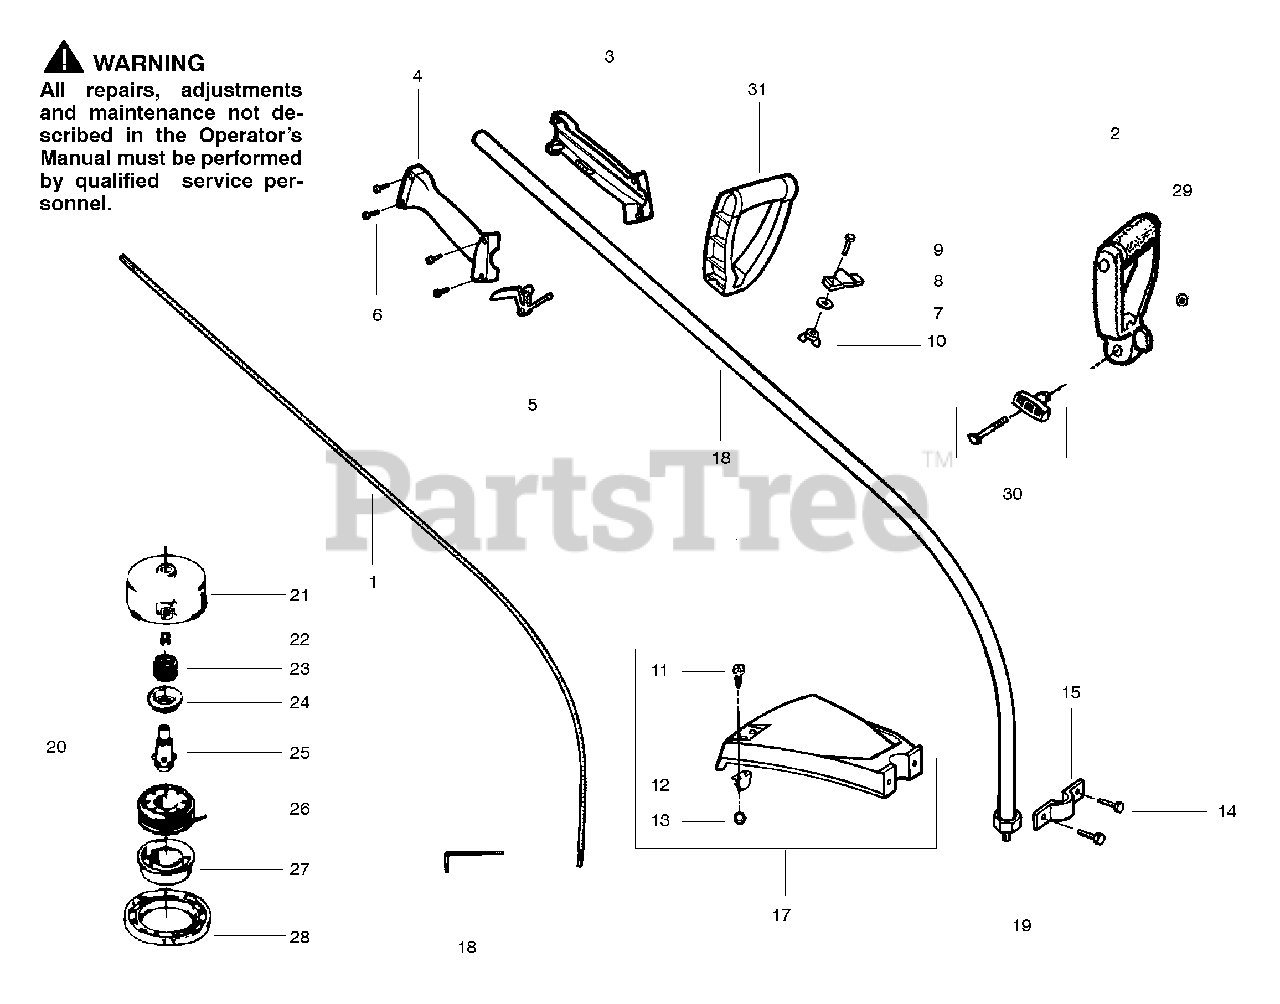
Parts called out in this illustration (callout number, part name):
1	Drive Shaft
3	Throttle Hsg. (Left)
4	Throttle Hsg. (Right)
5	Throttle Lever
12	Line Limiter
13	Locknut
15	Bracket Shield
16	Hex Wrench (5/32)
17	Shield Kit Ass'y.
18	Drive Shaft Hsg.
19	Dust Cup
20	Cutting Head Ass'y.
21	Hub Ass'y.
22	Line Saver
24	Spring Cap
25	Drive Gear
26	Spool w/Line
27	Release Button
30	"T" Handle Ass'y.
31	Handle
